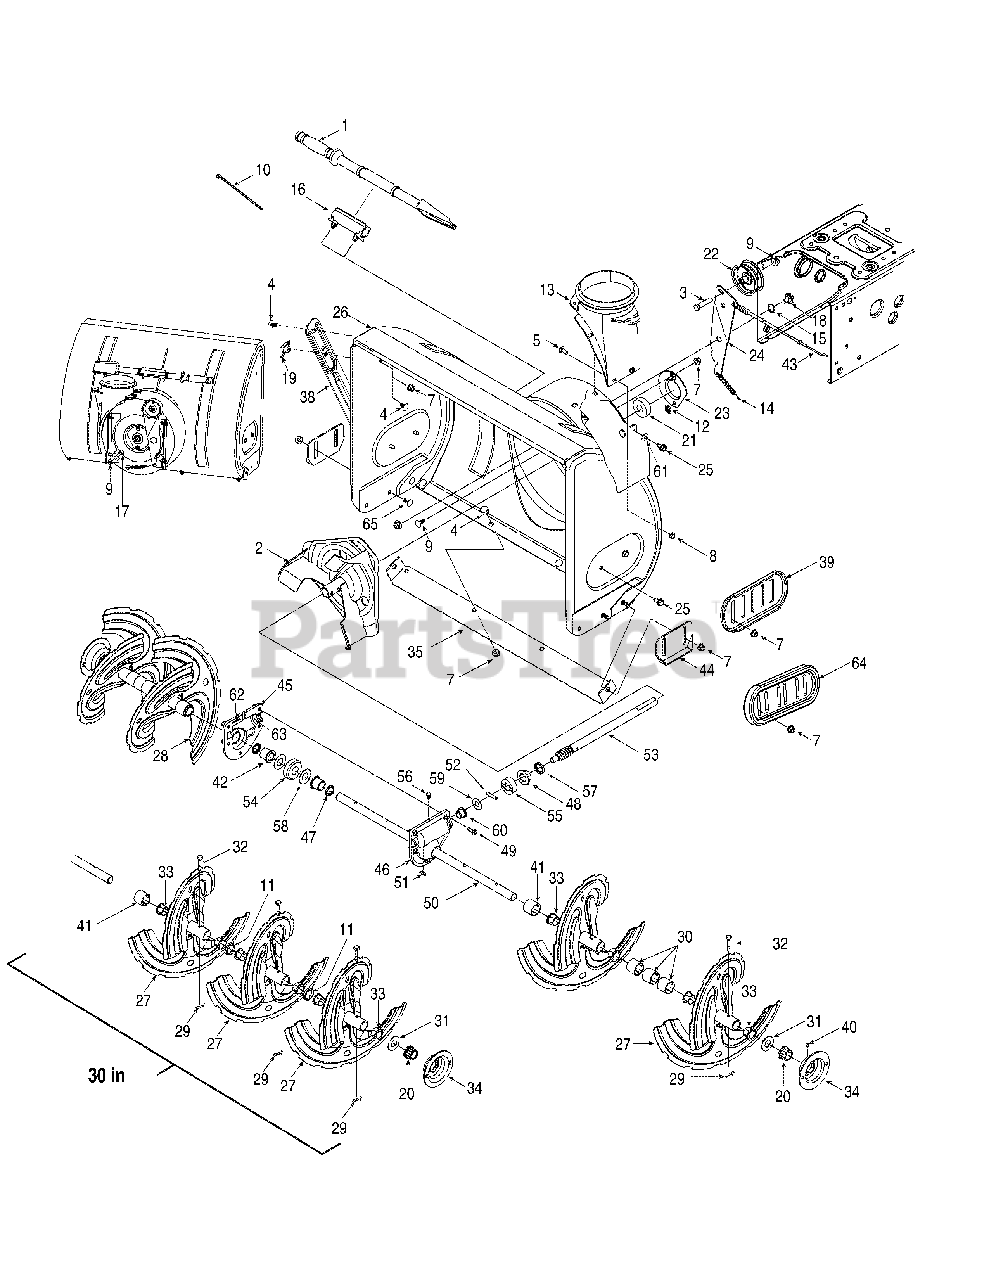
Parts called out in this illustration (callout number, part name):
1	Clean-Out Tool
3	Hex Screw 3/8-16 x 1.75
4	Carriage Bolt 5/16-18 x .75
5	Carriage Screw 1/4-20 x .75 Gr. 5
7	Flange Locknut 5/16-18 Gr. F Nylon
8	Hex L-Flanged Nut 1/4-20 Gr. F Nylon
9	Hex L-Flanged Nut 3/8-16 Gr. F Nylon
10	Cable Tie
11	Spacer 1.25 x .75 x 3-16'' Lg
12	Pushon Nut .25 Dia
13	Chute Adapter
14	Extension Spring .38 OD x 4.59'' LG
15	Wave Washer .660 ID x .88 OD x .010
16	Clean-Out Tool Mount
17	Shoulder Screw .500 Dia x .335'' Lg
18	Shoulder Screw .625 Dia x .170
19	Hand Knob
20	Hex Flange Brg. .751'' ID
21	Self-aligning bearing
22	Flat Idler Pulley 2.75'' OD
23	Bearing Housing 1.85 ID
25	Hex TT Screw 3/8-16 x .75
26	24'' Auger Housing
29	Bow Tie Cotter Pin
30	24'' Auger Axle
30	26'' Auger Axle
30	28'' Auger Axle
30	30'' Auger Axle
31	Flat Washer .760 ID x 1.49 OD
32	Sheer Pin .25 x 1.5 Gr. 2
33	Flange Bushing
40	Grease Fitting(optional)
41	Spacer 1.25 x .75 x 1.00
42	Flange Bearing .75 ID x 1.0 OD x .975
43	Auger Clutch Cable
45	RH - Reduced Auger Housing
46	LH - Reduced Auger Housing
47	Oil Seal .75 x 1.0 x .125
48	Flange Bearing .75 ID x 1.00 OD x .50
49	Thread Forming Screw, 1/4-20 x .75
50	24'' Gearbox Assembly
50	26'' Gearbox Assembly
50	28'' Gearbox Assembly
50	30'' Gearbox Assembly
51	Hi-Pro Key 3/16 x 5/8
52	Dowel Pin .25 OD x 1.2
53	Worm Shaft .75 OD
54	24'' Worm Gear
54	26'' Worm Gear
54	28'' Worm Gear
54	30'' Worm Gear
55	Thrust Collar
56	Plug 1/4 x .437
57	Oil Seal .75 x 1 x .131
58	Flat Washer .76 ID x 1.5OD x .03
59	Flat Washer .510 x 1.120 x .060
60	Flange Bearing .75 ID x 1.0 OD x .925
61	Cupped Washer .345 ID x .88 OD x .060
62	Loctite Sealant 5699
63	Grease- Alvania EP Lead Free
64	Reversible Slide Shoe
64	Deluxe Polymer Reversible Shoe Kit
65	Carriage Bolt 5/16-18 x .75
65	Carriage Bolt 5/16-18 x 1.0
